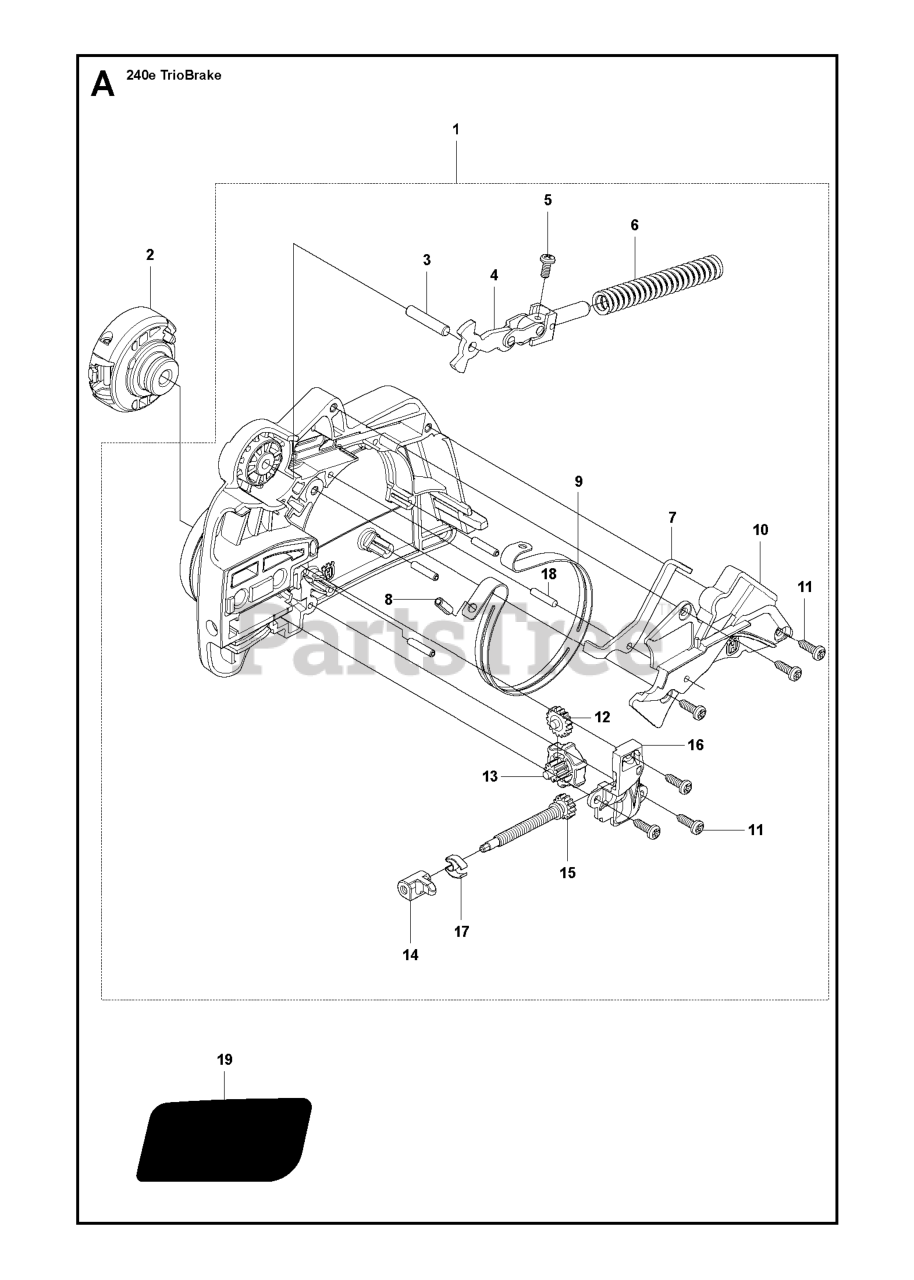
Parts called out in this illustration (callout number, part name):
1	ASSY CHAIN BRAKE TRIO
2	ASSEMBLY KNOB EZT
5	SCREW
9	BRAKE BAND
11	SCREW 6-19X.437
12	GEAR IDLER
13	ADJUSTMENT WHEEL
14	PIN BAR ADJUSTING EZT
16	COVER, GEAR
19	DECAL, EZT CLUTCH
